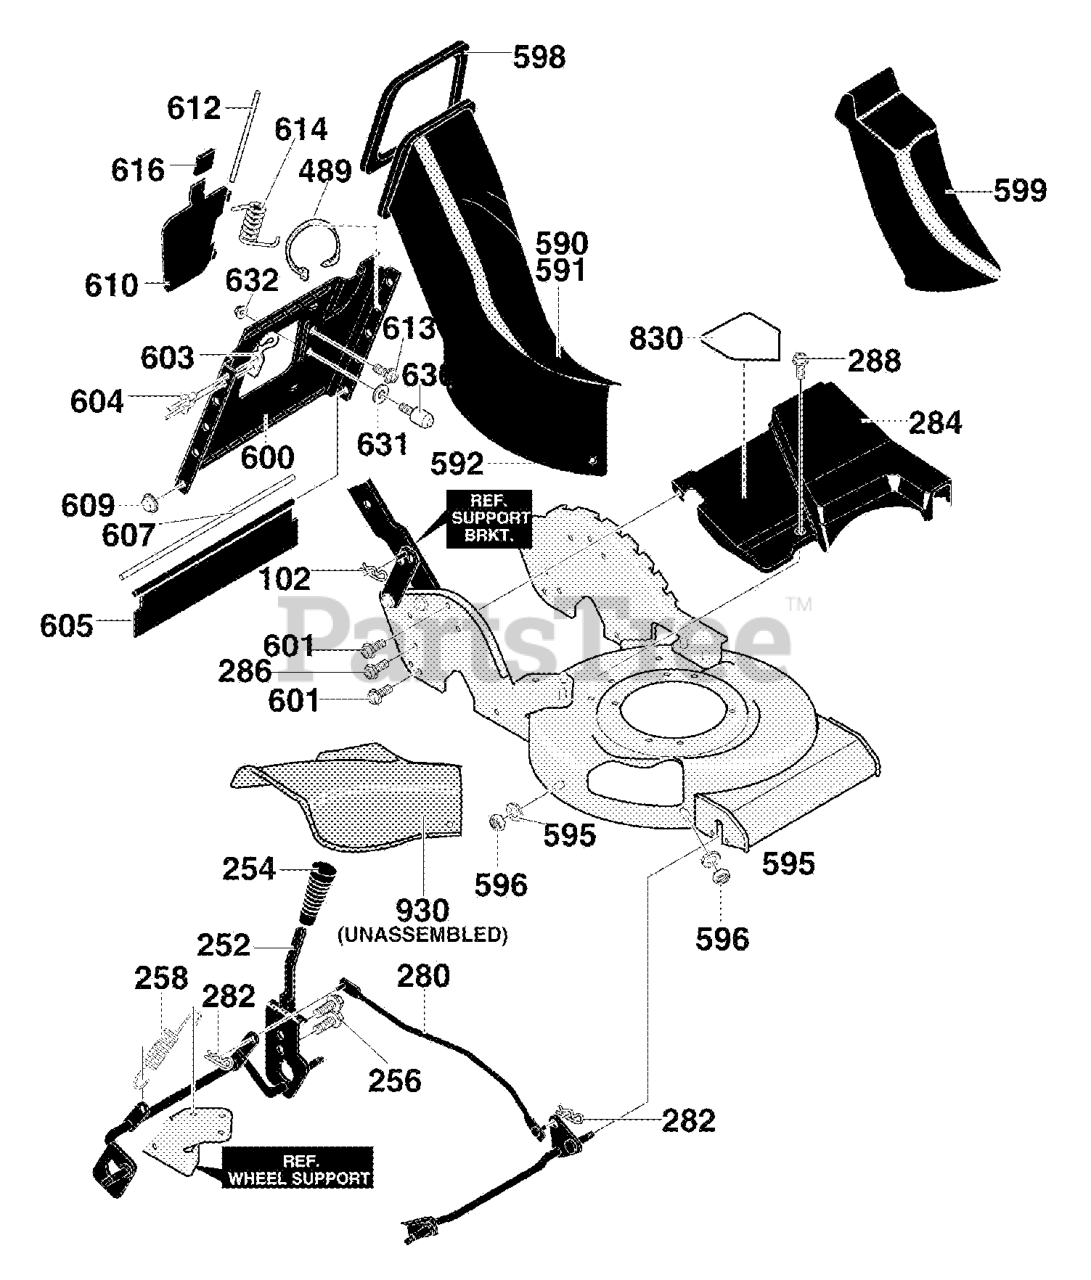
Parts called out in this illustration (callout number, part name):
102	HAIR PIN
252	SPRING, Lever Hgt/Adj Rear
254	KNOB, Height Adjust
256	SCREW, 1/4-20x.63
258	SPRING, Extension
280	Lifter, Assy Link
282	HAIR PIN
284	Cover, Rear
286	SCREW, 1/4-20x.63
288	SCREW, 10-16x.75
489	Cable Tie
590	CHUTE, RR Discharge
591	CHUTE Floor, Rear
592	Rivet Pop
595	FLATWASHER
596	NUT, 5/16-18
598	Gasket, Compression
599	Plug, Mulcher
600	Plate, Bag
601	SCREW, 5/16-18 x 0.62
603	Lower Rope Guide
604	Pop Rivet
605	GUARD, Rear Toe
607	ROD, Rear Guard
609	Cap, Push On
612	PIN, Hinge Door
613	SCREW, #8-32x.38
614	Torsion Spring
616	Door Grip
630	PIN, Hinged Hood Latch
631	FLATWASHER
632	NUT, 5/16-18
830	DECAL, Cut Finger
930	CHUTE, Side Discharge
